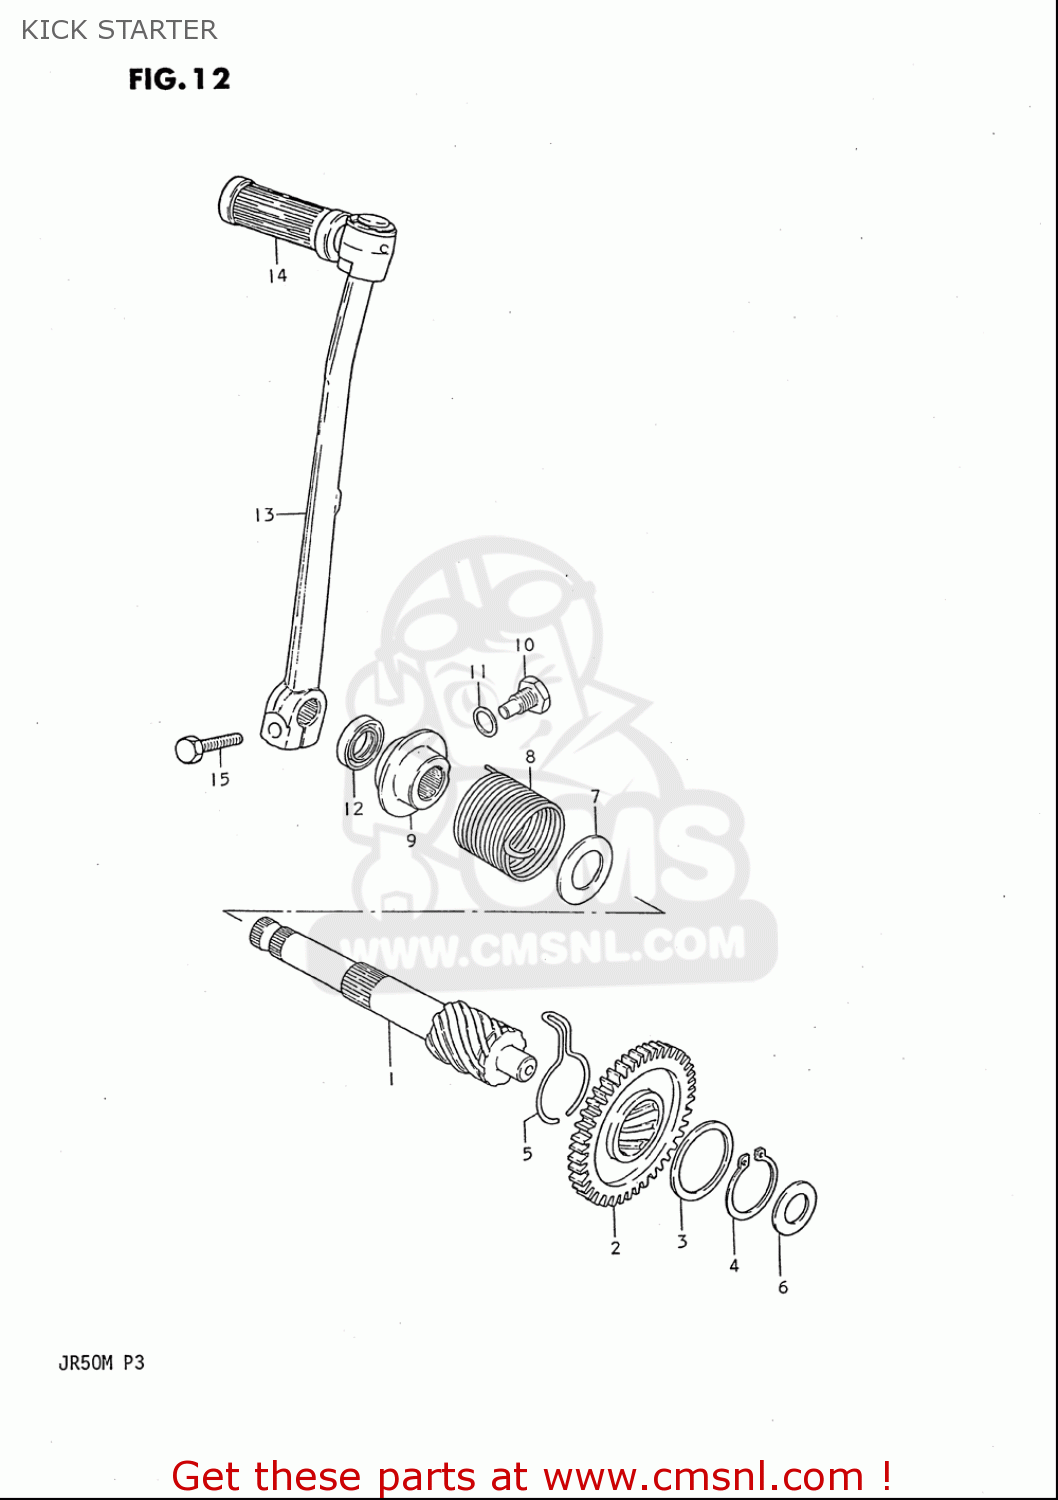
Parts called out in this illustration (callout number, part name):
1	SHAFT,KICK STARTER
2	GEAR,KICK STARTER DRIIVE
3	WASHER
4	CIRCLIP
5	RETAINER,SNAP
6	WASHER
7	WASHER(16X30X1)
8	SPRING
9	LIFTER,KICK STARTER
10	BOLT(10X17)
11	GASKET(10X14X3.6) (NAS)
12	SEAL,OIL(14X24X6)
13	LEVER ASSY,KICK STARTER
14	RUBBER,KICK STARTER PEDAL
15	BOLT
